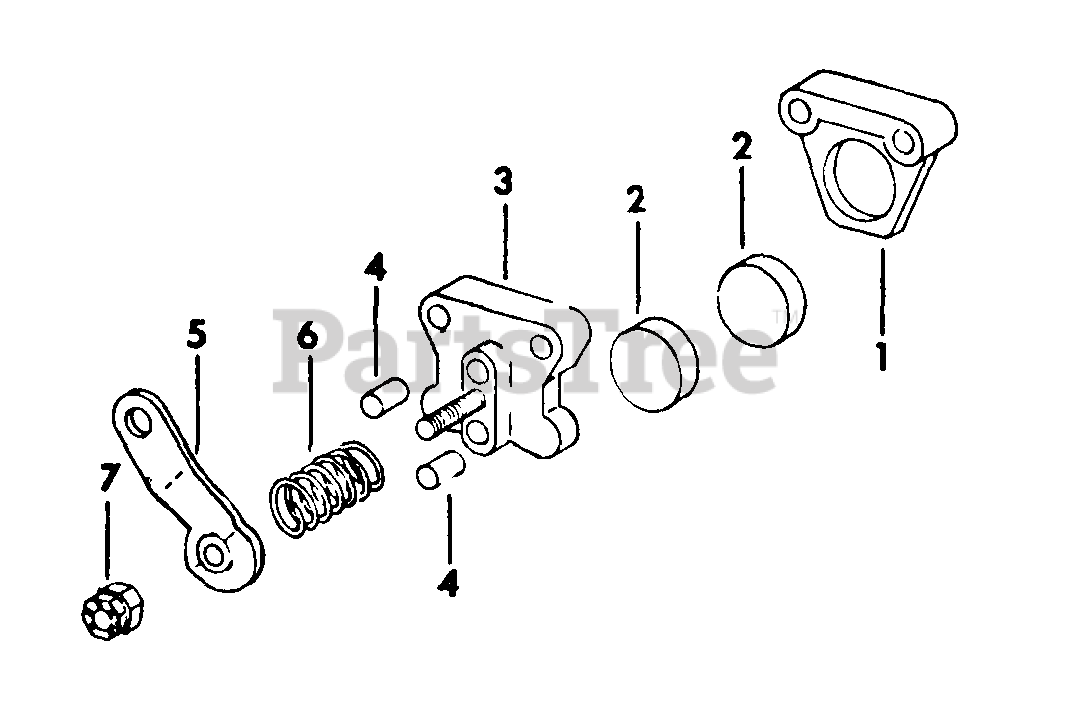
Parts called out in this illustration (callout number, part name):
1	SIDE, PUCK CARRIER
2	PUCK
6	SPRING, COMPRESSION RETURN
